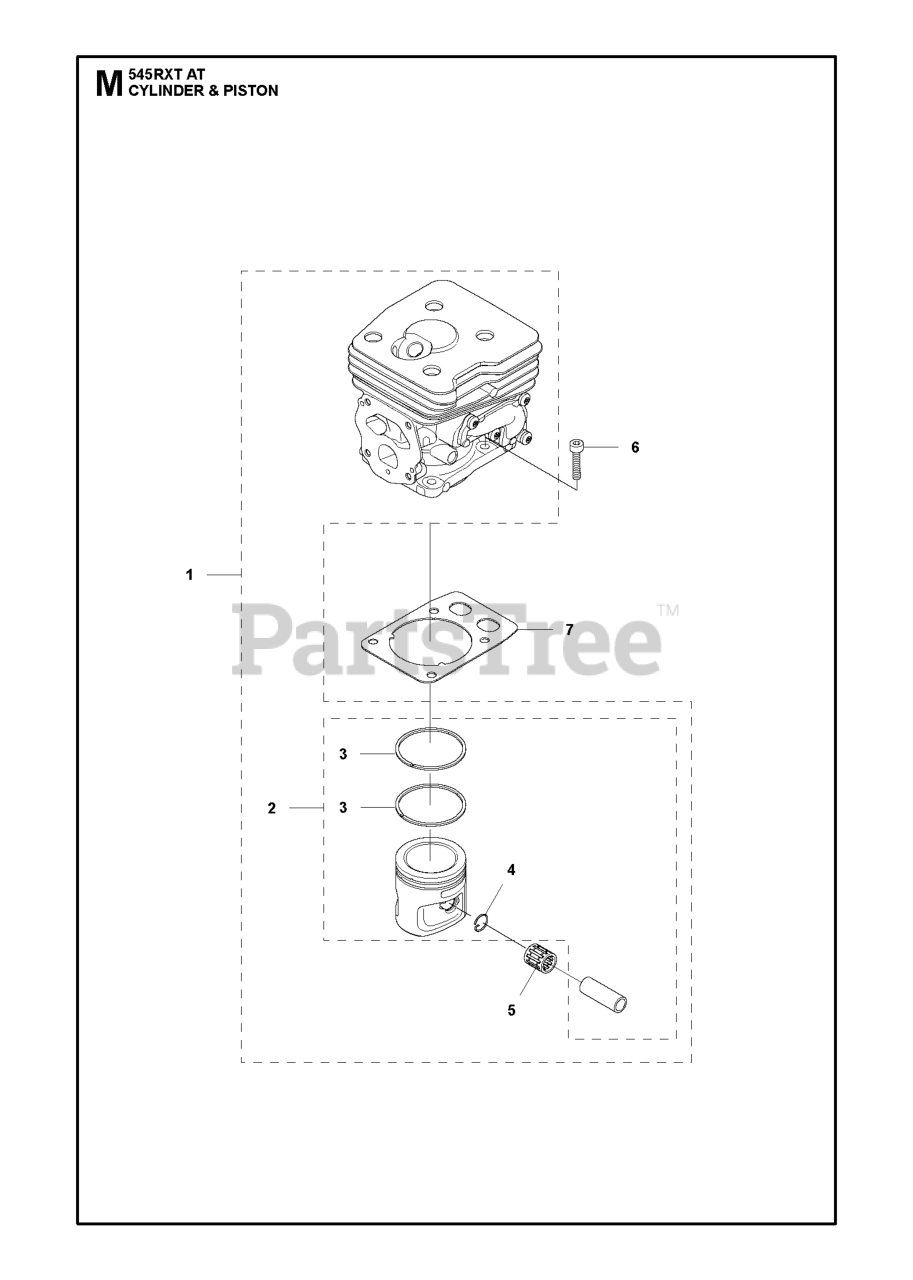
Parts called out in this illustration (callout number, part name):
1	CYLINDER KIT SPARE PART 545 AT
2	PISTON ASSY
3	PISTON RING D42
4	LOCKING RING
5	NEEDLE BEARING
6	SCREW MC6S 5X25
7	GASKET CYLINDER
